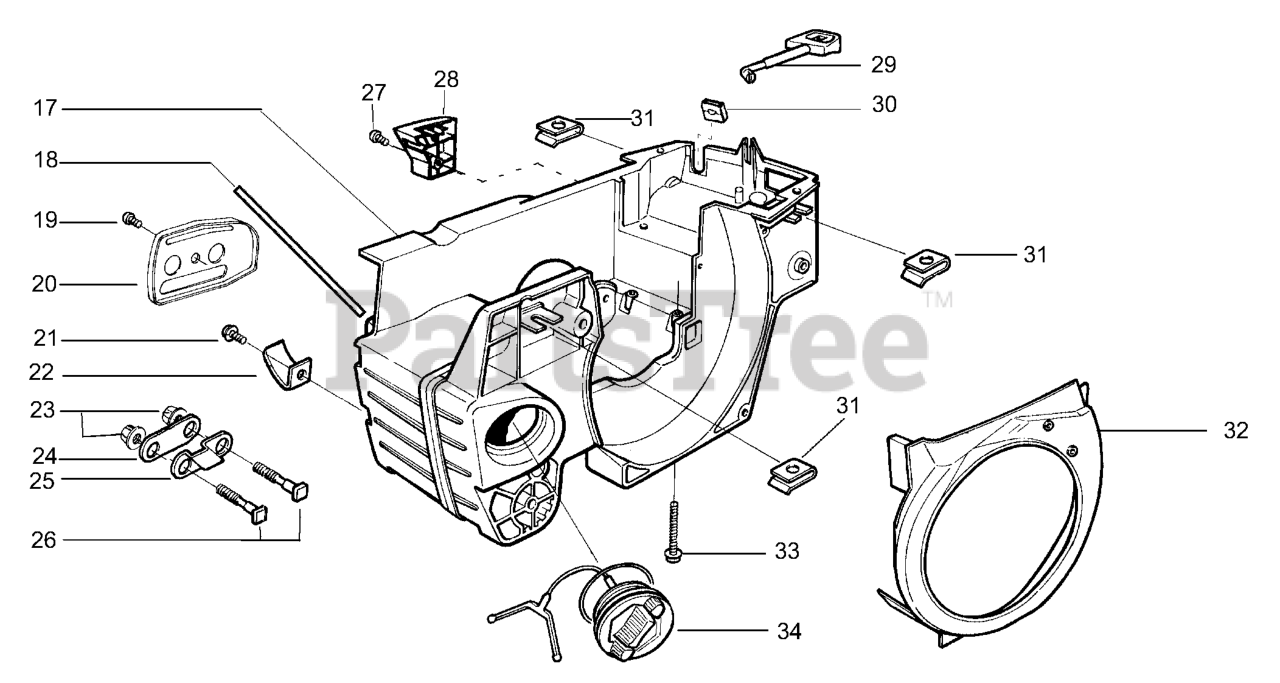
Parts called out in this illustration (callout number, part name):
17	CRANKCASE ASSY
18	TUBE
19	SCREW
22	CHAIN CATCHER 36/41
24	OIL TANK GASKET
25	PLATE,BAR MOUNT
26	BAR BOLT 36/41
28	LIMITER COVER
29	CHOKE 36/41
30	CHOKE GUIDE 36/41
32	AIR CONDUCTOR 36/41
33	SCREW M5-0.8X35M TAP
